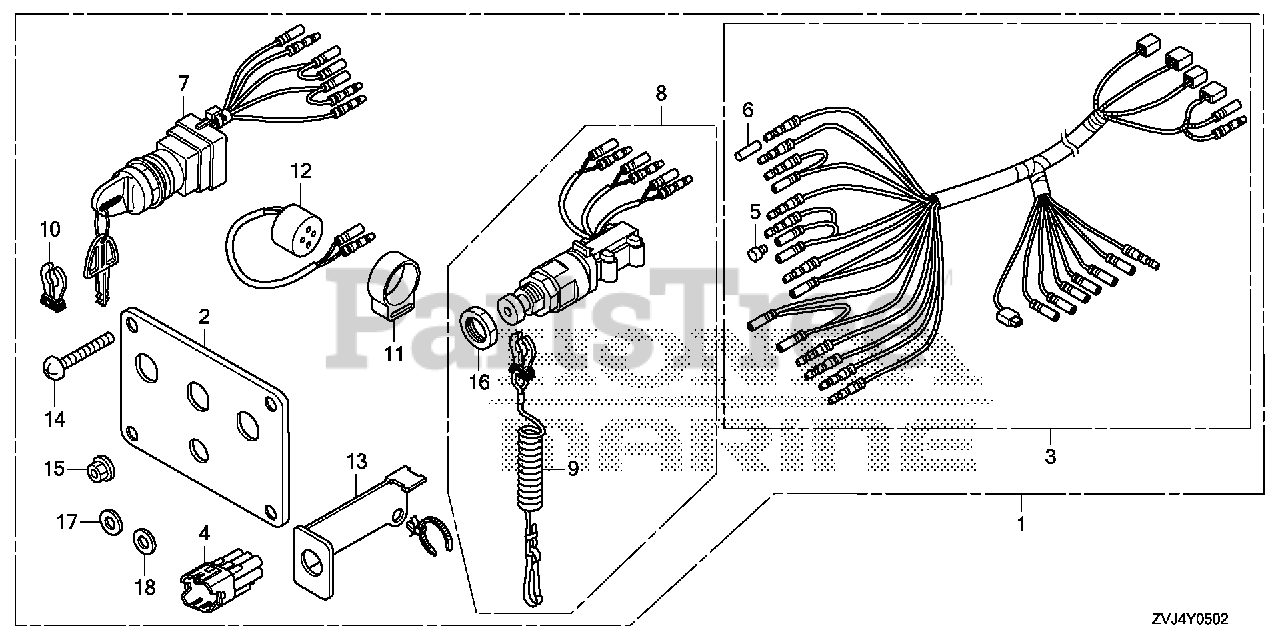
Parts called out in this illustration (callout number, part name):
1	PANEL KIT, SWITCH (TRIPLE)
2	PANEL, CONTROL (TRIPLE)
3	HARNESS ASSY., SWITCH PANEL
4	DUMMY, WATERPROOF CONNECTOR (GREEN)
5	PLUG, CONNECTOR (INNER)
6	PLUG, CONNECTOR (OUTER)
7	SWITCH ASSY., COMBINATION
8	SWITCH ASSY., EMERGENCY STOP (TRIPLE)
9	WIRE, EMERGENCY
10	CLIP, EMERGENCY LOCK
11	SUSPENSION, AUDIBLE PILOT
12	BUZZER, WARNING
13	BRACKET
14	SCREW, PAN (5X40)
15	NUT, FLANGE (5MM)
16	NUT
17	WASHER, PLAIN (5MM)
18	WASHER, SPRING (5MM)
